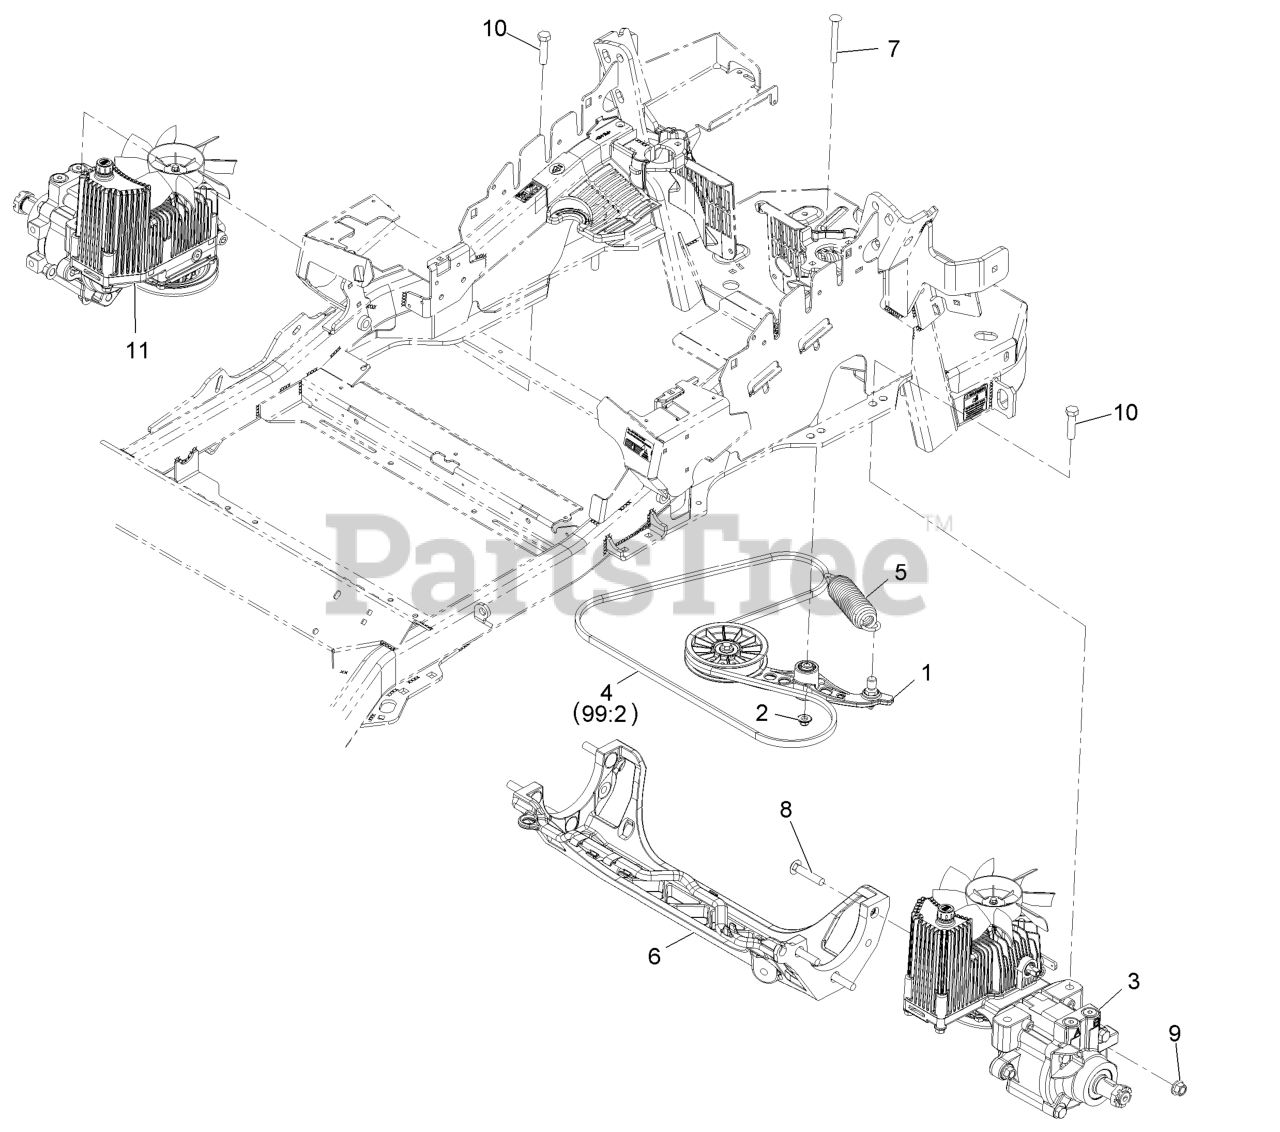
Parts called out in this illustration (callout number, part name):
1	PUMP IDLER ASM
2	Nut-Nyloc 3/8-16 Flg
4	BELT
7	BOLT-SHOULDER, CARRIAGE 3/8-16 X 3 1/2
8	SCREW-CARR
9	Nut-Lock 1/2-13
10	SCREW-HH
99:2	BELT
